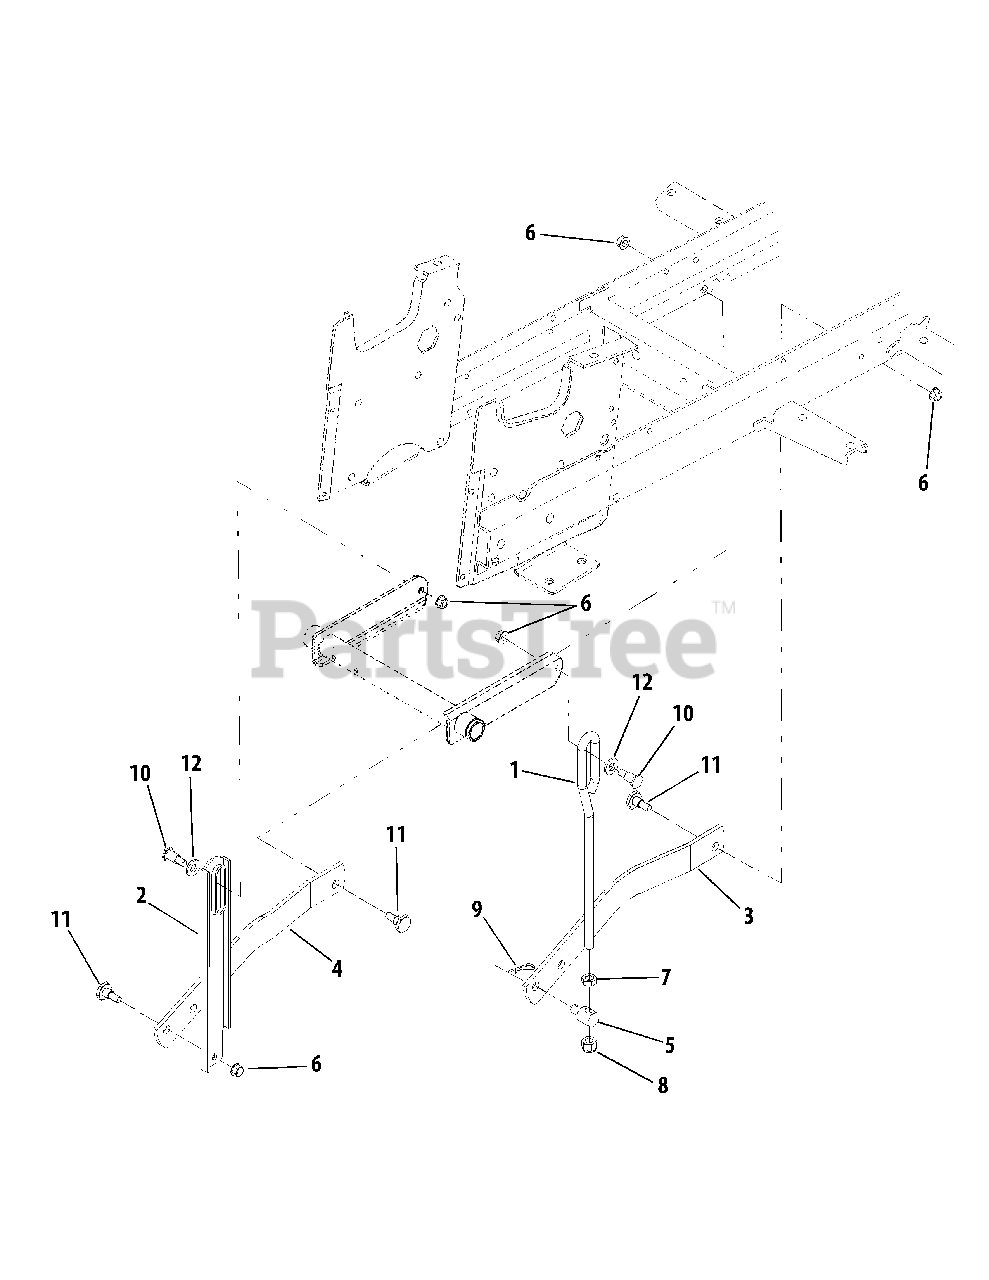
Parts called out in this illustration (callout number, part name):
1	Rod, Lift Link
4	Link, LH Lift
5	Ferrule, Adjustment
6	Nut, Hex Flange Lock, 3/8-16
7	Nut, Hex Jam, 1/2-13 GR5
8	Nut, Hex Insert Lock, 1/2-13
9	Pin, Internal Cotter
10	Bolt, Shoulder
11	Bolt, Shoulder
12	Washer, Flat, .51 x 1.0 x .125
